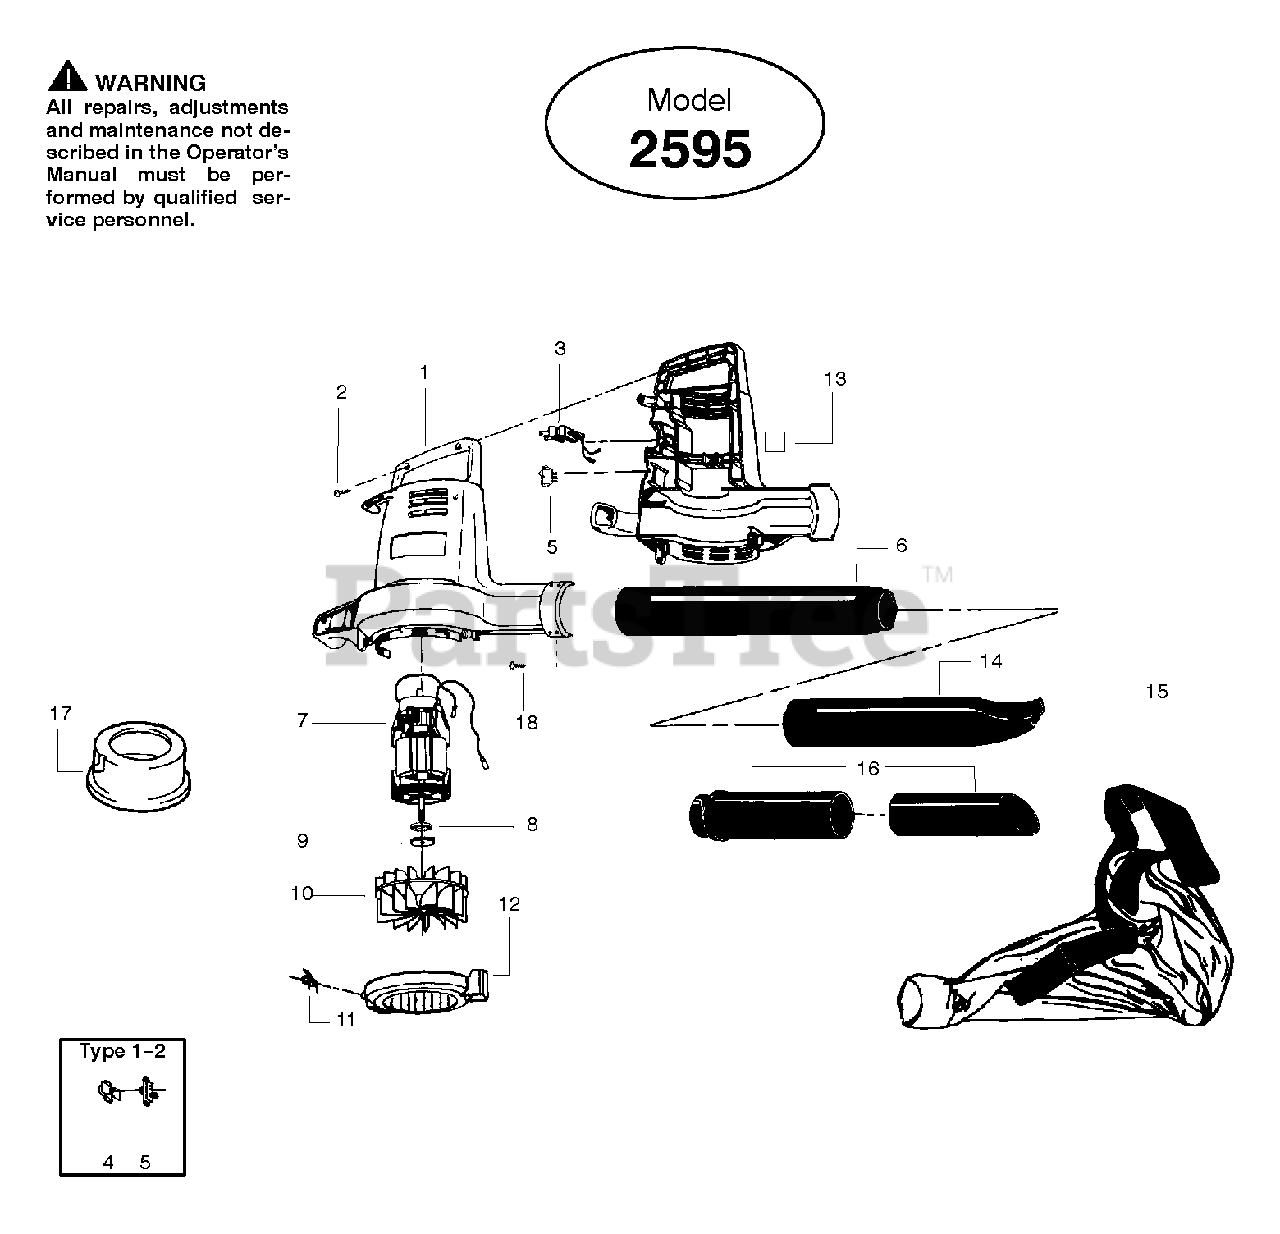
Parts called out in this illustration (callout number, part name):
1	Housing Set (Type 1,2)
1	Housing Set (Type 3,4)
3	Wire Harness (Type 1,2)
3	Wire Harness (Type 3,4)
4	Switch Cover(Type 1,2)
5	Switch (Type 1,2)
5	Switch (Type 3,4)
6	Blower Tube
7	Motor Ass'y. Type 1
7	Motor Ass'y. Type 2,3
7	Motor Ass'y. Type 4
8	Spacer (Type 2,3 only)
10	Impeller
12	Assy-Cover Spring
13	Pad (Type 1 only)
15	Vacuum Bag Kit
16	Vacuum Tube Kit
17	Inlet Restrictor
